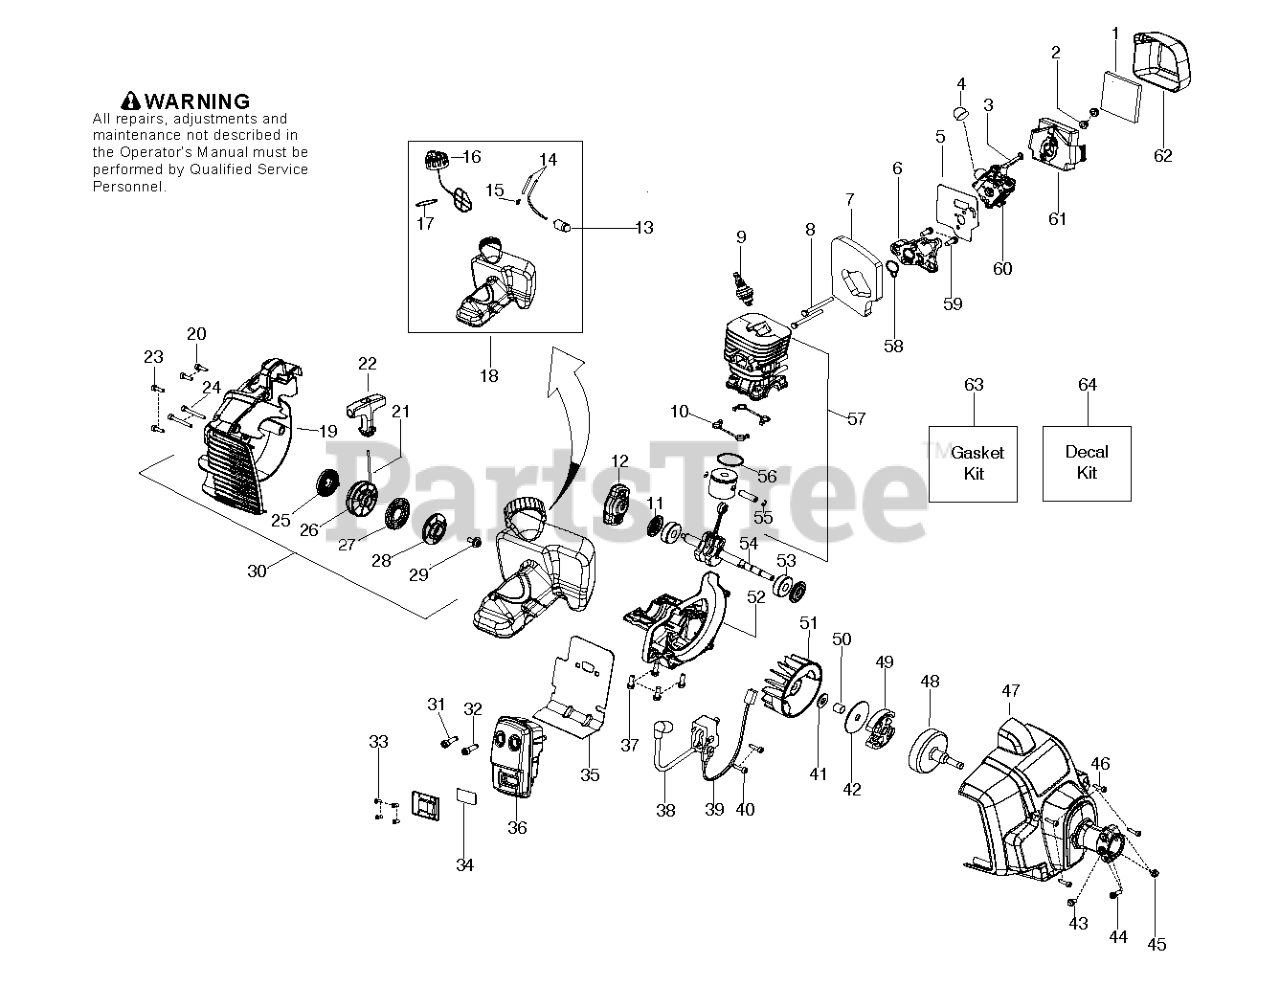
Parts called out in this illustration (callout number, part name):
1	FILTER FOAM
2	Nut - Carb. Screw
3	LEVER CHOKE
4	Bulb - Purge, Zama
5	KIT GASKET CARB 28CC
6	CARB ADAPTOR
7	KIT GASKET 28CC
8	BOLT CARB ADAPTOR
9	Spark Plug, - Type 2-3 & Model GTI16D
10	SEAL CYLINDER
11	KIT GASKET 28CC
12	STARTER PAWL BRIDGE
13	ASSY FUEL PICKUP PRE FLUSHED
14	Kit - Fuel line
15	FUEL LINE FITTING DBL BARB
16	ASSY FUEL CAP
17	KIT GASKET 28CC
18	KIT FUEL TANK PP 28CC
19	HOUSING STARTER
21	KIT ROPE
22	Handle - Starter
24	SCREW M5-0.8X30MM
25	KIT STARTER SPRING
26	STARTER PULLEY KIT
27	DRIVER SPRING
28	PULLEY STARTER DRIVE
30	KIT HOUSING STARTER
31	Bolt - Muffler
32	Bolt - Muffler
33	Screw - #6 - 19 x 5/16" - Pan. Hd. - Reed Valve
34	KIT SPARK ARRESTOR SCREEN
35	KIT GASKET 28CC
36	KIT MUFFLER W/CATALYST
37	SCREW-M5-0.8 X 25MM(TAP)
38	IGNITION MODULE MBU-7
39	ASSY MOD LEADWIRE
40	SCREW M4 X .70 TT 16MM
41	Washer-Clutch Flat
42	Clutch Washer-Models HP22T, HP30SB
43	Screw - Alignment (10-14 x 1/2")
44	Screw - Phil. Hd. - 5 x 25mm.- Throttle Control
45	Nut Type 1 Model XT125K,XT125KT
46	SCREW M4 X .70 TT 16MM
47	ASSY FAN HSG BLK
48	KIT DRUM CLUTCH ASSY
49	ASSEMBLY CLUTCH
50	Spacer - Flywheel
51	FLYWHEEL
52	CRANKCASE CAST 128
53	Bearing - Crankshaft
54	CRANKSHAFT
55	Retainer - Wrist Pin (PRO150 Only)
56	RING PISTON
57	KIT PISTON AND CYLINDER
58	KIT GASKET 28CC
59	SCREW-M5-0.8 X 25MM(TAP)
61	HOUSING AIR FILTER BLACK
62	COVER FILTER HSG
63	KIT GASKET 28CC
64	DECAL
